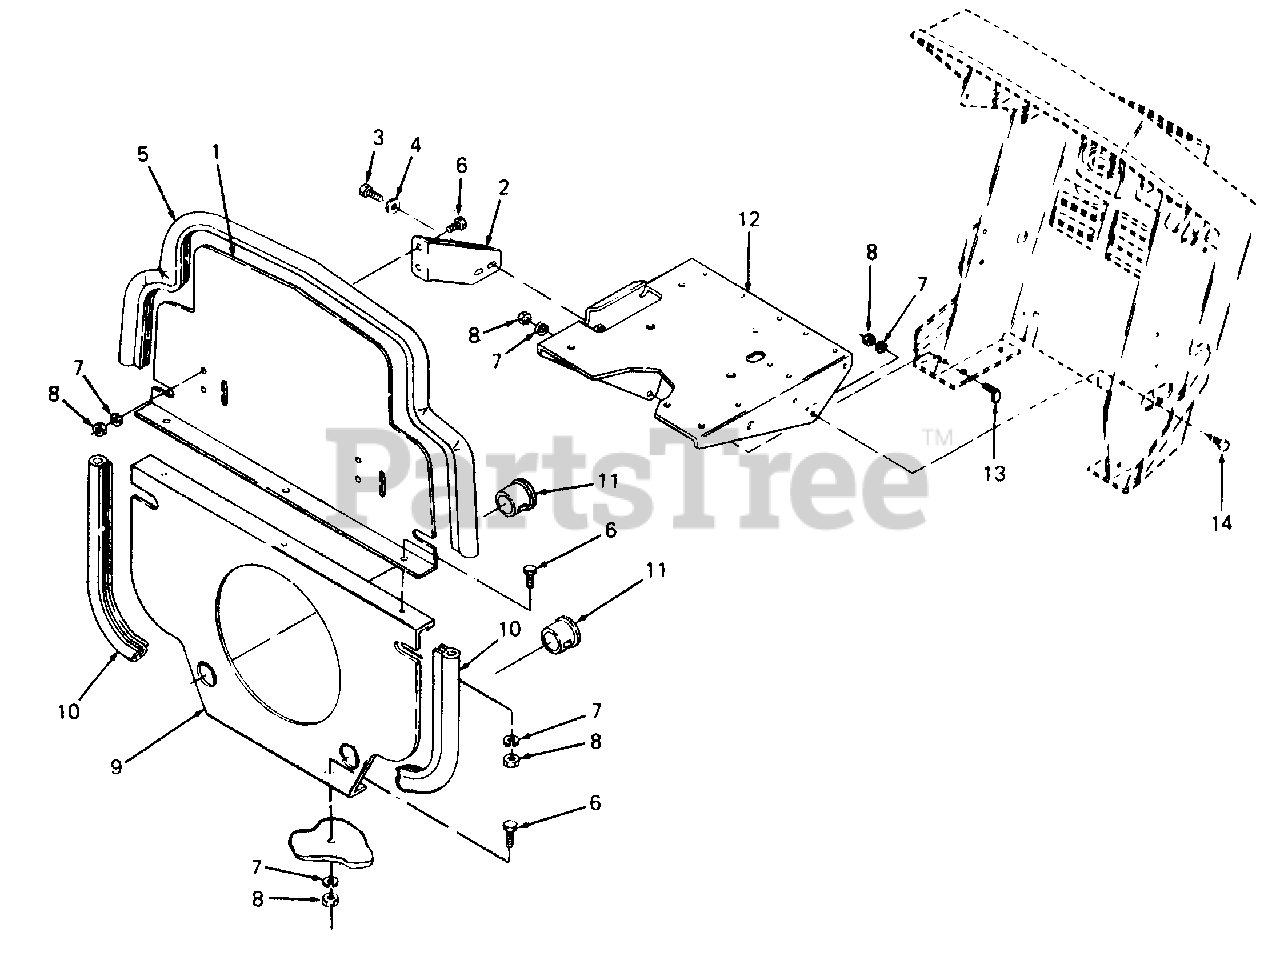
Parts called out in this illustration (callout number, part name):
3	Screw, Hex Cap, 5/16-18 X.SO Lg GR5
4	Washer, Bell, .345 X .88 X .060 Thk
5	Seal, Bulkhead, 36" Lg
6	Screw, Hex Cap, 1/4-20 X .50 Lg GR5
7	Washer, Lock, 1/4
8	Nut, Hex, 1/4-20 GR5
9	Bulkhead, Lower
10	Seal, Bulkhead, 10" Lg
11	Bushing, Snap, 7/8 ID
12	Tray Assy, Battery
13	Bolt, J-Type, 1/4-20
14	Screw, Hex Cap, 1/4-20 X .62 Lg GR5
